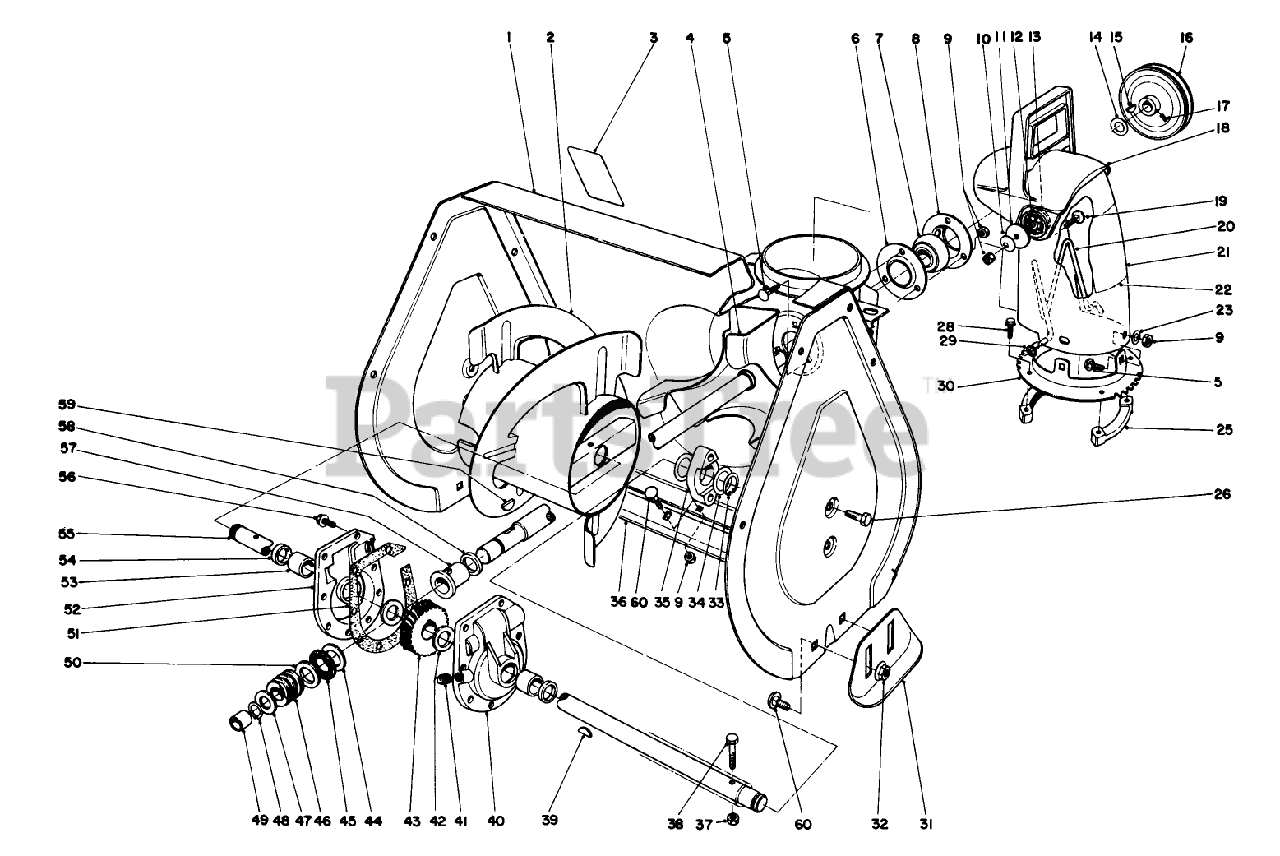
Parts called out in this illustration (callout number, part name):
1	Housing-Auger (Incl. Ref. #3)
2	Auger R.H.
3	DECAL-WARNING, AUGER
4	Shaft & Impeiler
5	SCREW-CARR
6	Flange-Bearing Front
7	BEARING-BALL
8	Flange-Bearing Rear
9	NUT-LOCK, NI
10	WASHER-BELLEVILLE
11	WASHER-FLAT
12	PLATE-FRICTION
13	WASHER-RUBBER
14	WASHER
15	KEY-WOODRUFF
16	PULLEY
17	SCREW-SET, SQH
18	CHUTE-DEFLECTOR
19	SCREW-CARR
20	WIRE-CHUTE
21	Chute-Discharge (Incl. Ref. #22) Model 38052
22	Decal-Danger
23	WASHER-PLAIN
25	RING-CHUTE, RETAINER
26	SCREW-HWHTF
28	SCREW-SPECIAL
29	NUT-PUSH
30	Chute Ring
31	Skid
32	NUT-HF
33	RING-RETAINING
34	WASHER
35	BEARING-AUGER
36	Blade-Scraper
37	NUT-LOCK, NI
38	SCREW-HH
39	KEY-WOODRUFF
40	Gear Case L.H. (Incl. Ref. #53 & 54)
41	PLUG-PIPE, SQH
42	WASHER-THRUST
43	GEAR-WORM, 27T
44	WASHER-THRUST
45	BEARING-THRUST
47	WASHER-THRUST
48	Ring-Snap
49	BUSHING
50	WASHER-THRUST
51	GASKET-CASE, GEAR
52	Gear Case R.H. (Incl. Ref. #53 & 54)
53	BUSHING
54	SEAL-OIL
55	AUGER SHAFT
56	SCREW-TAPTITE
57	BUSHING-INPUT
58	RING-QUAD
59	KEY-WOODRUFF
60	BOLT-CARR
